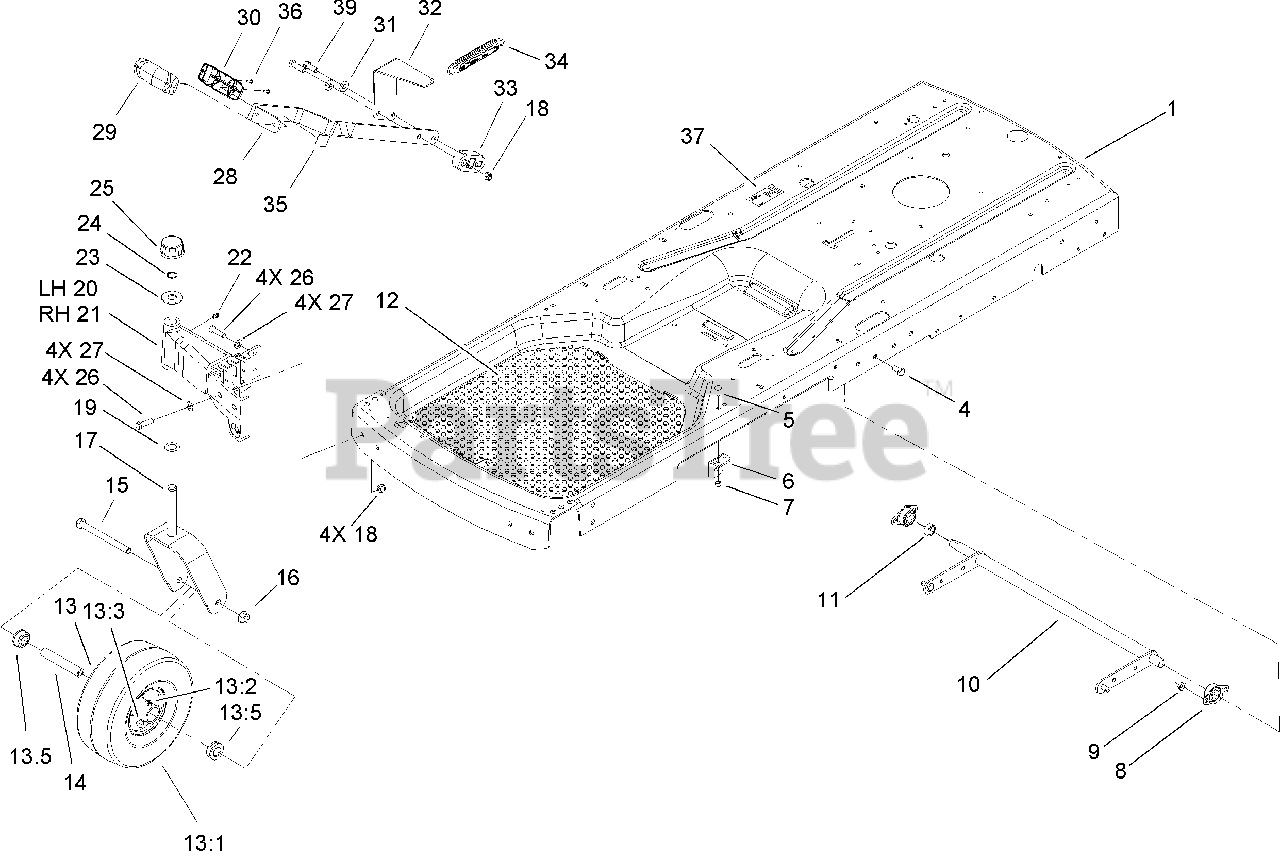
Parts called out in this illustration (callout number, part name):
4	SCREW-HH
5	SCREW-CARR
6	BRACKET-LIFT
7	NUT-LOCK, NI
8	BEARING-FLANGE, SIDE
9	NUT-HHF, WHIZ
10	LIFT ARM ASM
12	FOOTMAT-FRAME
13	CASTER WHEEL ASM
13:1	TIRE-SMOOTH
13:2	FITTING-GREASE
13:3	STEM-VALVE
13:5	BUSHING-FLANGE
14	SPANNER-WHEEL
15	SCREW-HH
17	CASTOR FORK ASM
18	NUT-LOCK, NI
19	WASHER-THRUST
22	FITTING-GREASE
24	RING-RETAINING, EXT
26	SCREW-HH
27	WASHER-FLAT
29	HANDLE-TOP
30	HANDLE-BOTTOM
31	WASHER-BELLEVILLE
32	MOUNT-SPRING, FRONT
33	BLOCK-LIFT
34	SPRING-EXTENSION
37	DECAL-TRANSPORT, CE
39	SCREW-HH
